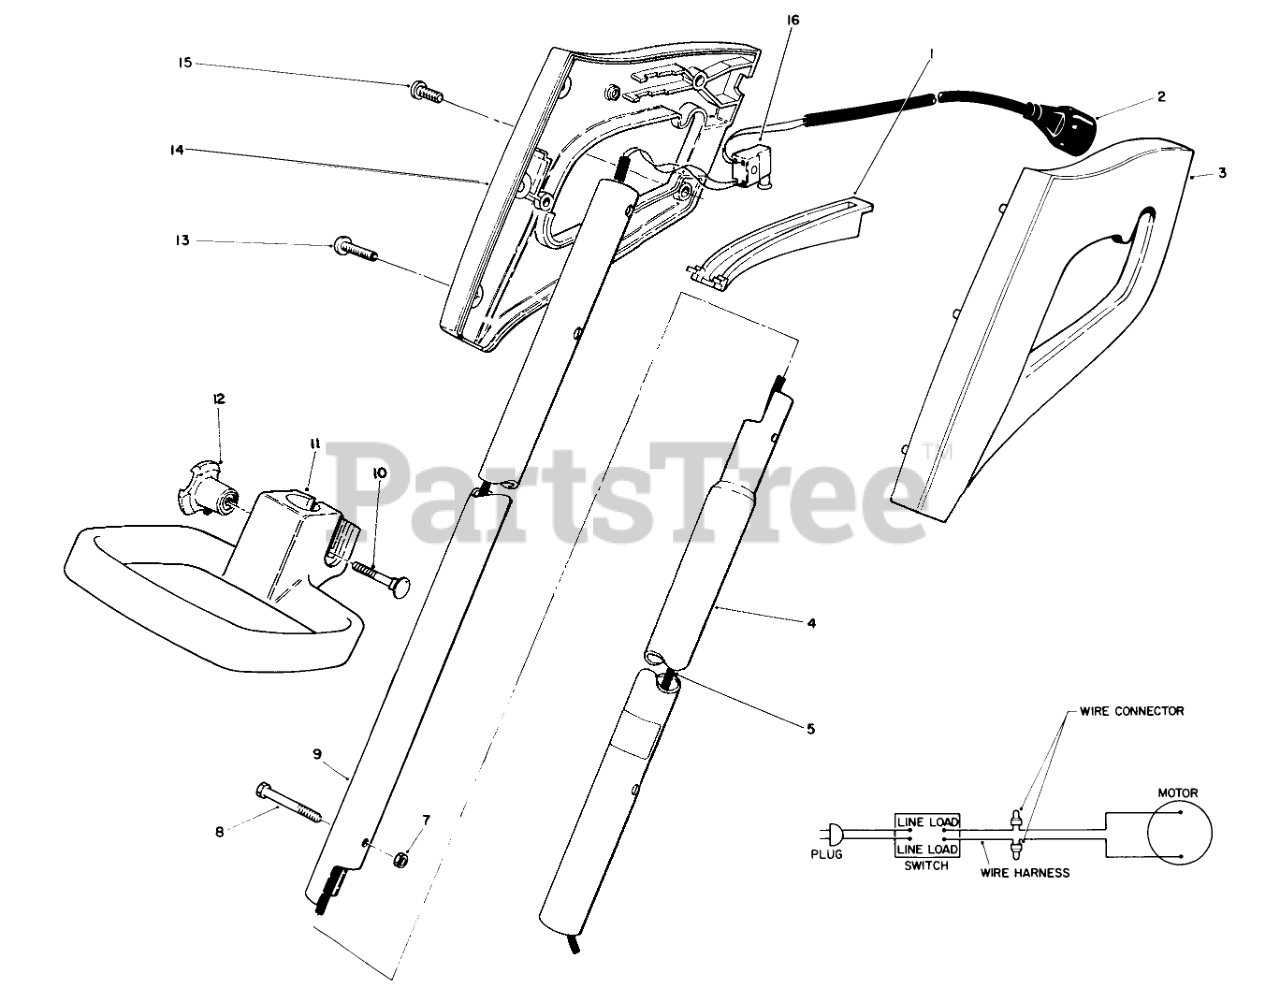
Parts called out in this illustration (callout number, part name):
1	TRIMMER-SWITCH BAR
2	Cord-Power
3	HANDLE GRIP, LH
4	TUBE-LOWER EXTENSION
5	1010 WIRE HARNESS
7	NUT-LOCK, NI
8	HEX HD MACHINE SCREW
9	TUBE-UPPER
10	BOLT-CARR
11	Handle-Adjust
12	Knob
13	Screw
14	HANDLE GRIP, RH
15	SCREW-PPH
16	SWITCH
